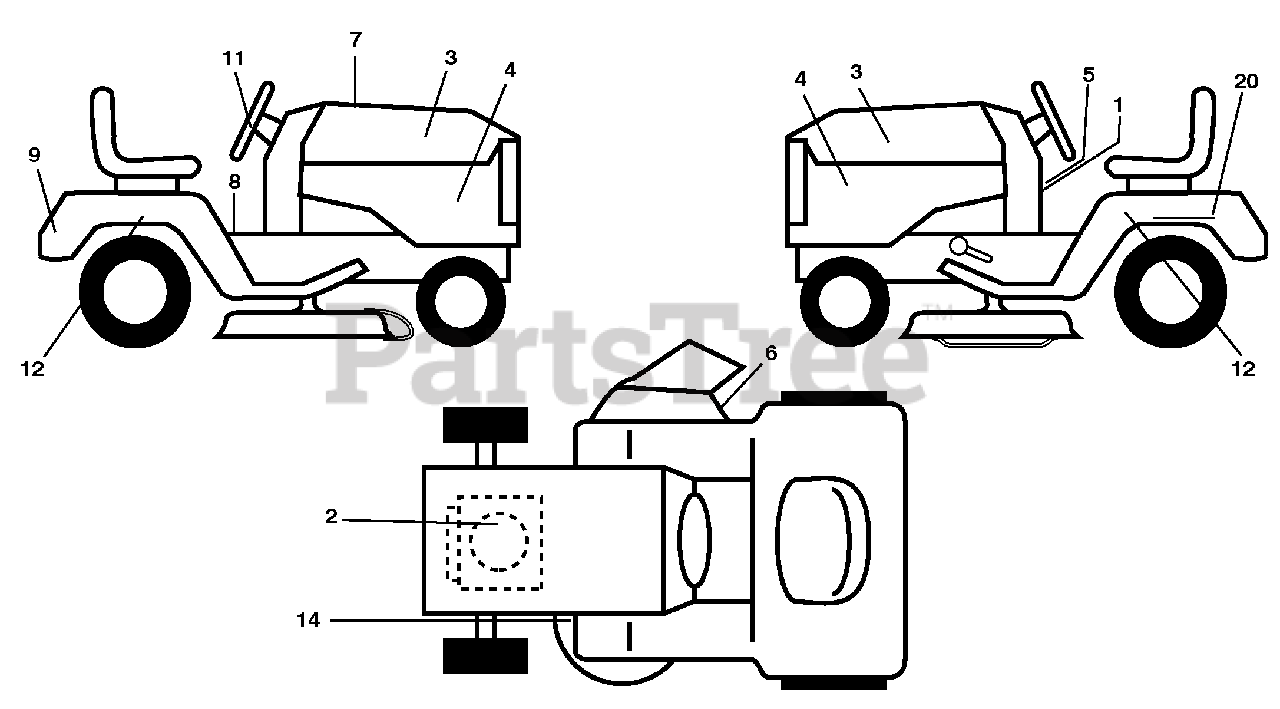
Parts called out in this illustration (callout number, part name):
1	Decal, Warning Spark Arrestor
2	Decal Eng. H.P.
4	Decal Side Panel Logo
5	Lable Emission
6	Decal Warning, Keep Hand Away
7	Decal Replacement Parts
8	Decal Fender Warn S/F
9	Decal Fender Logo
11	Decal Ins Strg Whl
12	Decal Fend SD
14	Decal V-Belt Schematic
20	Decal Bat Dan/Psn
20	Decal Bypass
20	Pad Footrest LH
20	Pad Footrest RH
20	Manual Operator's (English/French)
20	Manual Operator's (Spanish)
20	Manual Parts (English/French)
